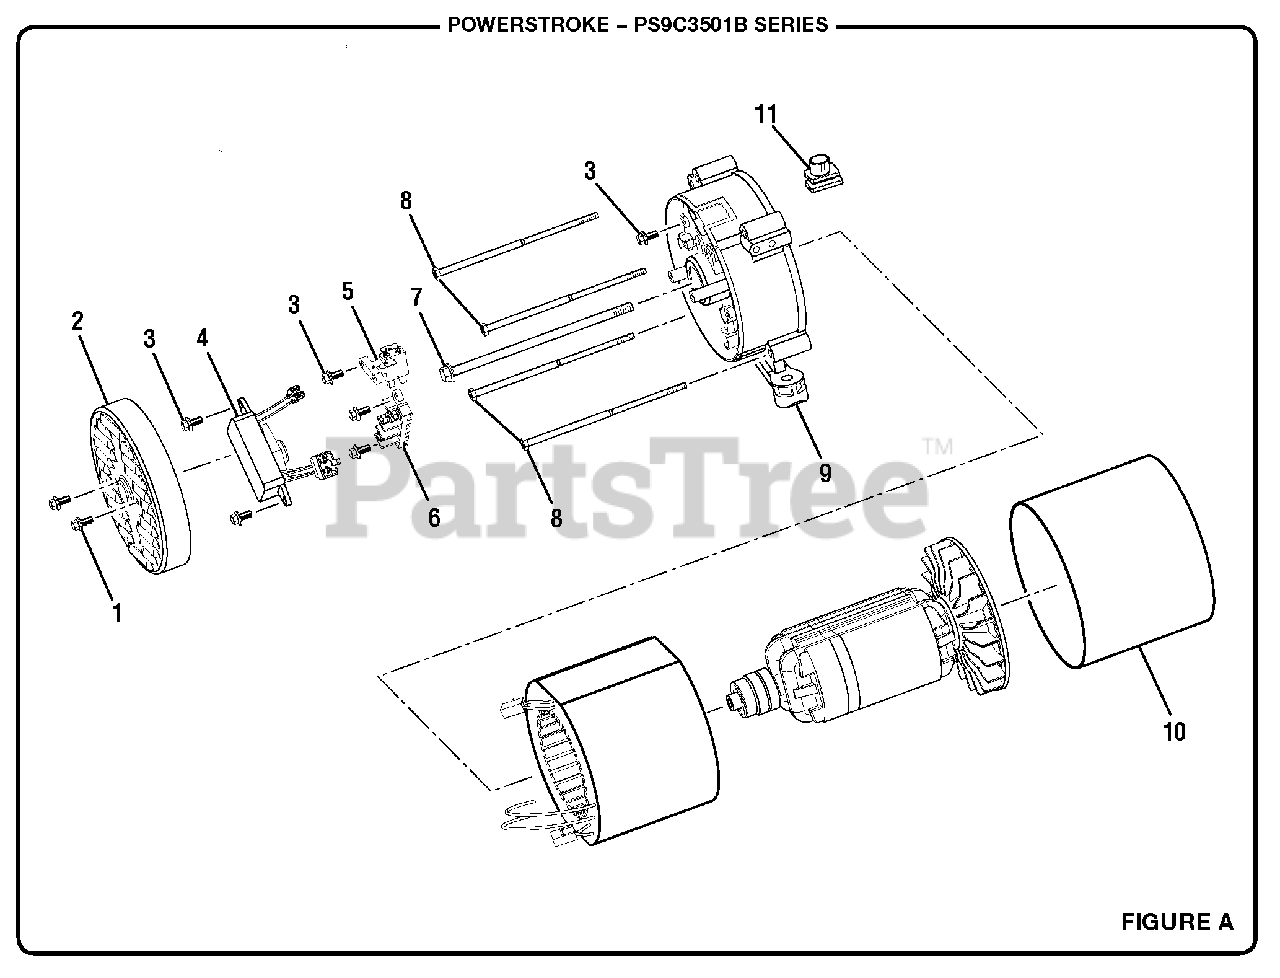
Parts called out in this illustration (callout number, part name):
1	Bolt (M5 x 16 mm, Hex Hd.)
2	Brush Cover
3	Bolt (M5 x 10 mm)
4	Automatic Voltage Regulator
5	Brush Assembly
6	Terminal Block
7	Rotor Bolt
8	Stator Bolt
9	Bearing Housing
10	Generator Head Cover
11	Rubber Boot
